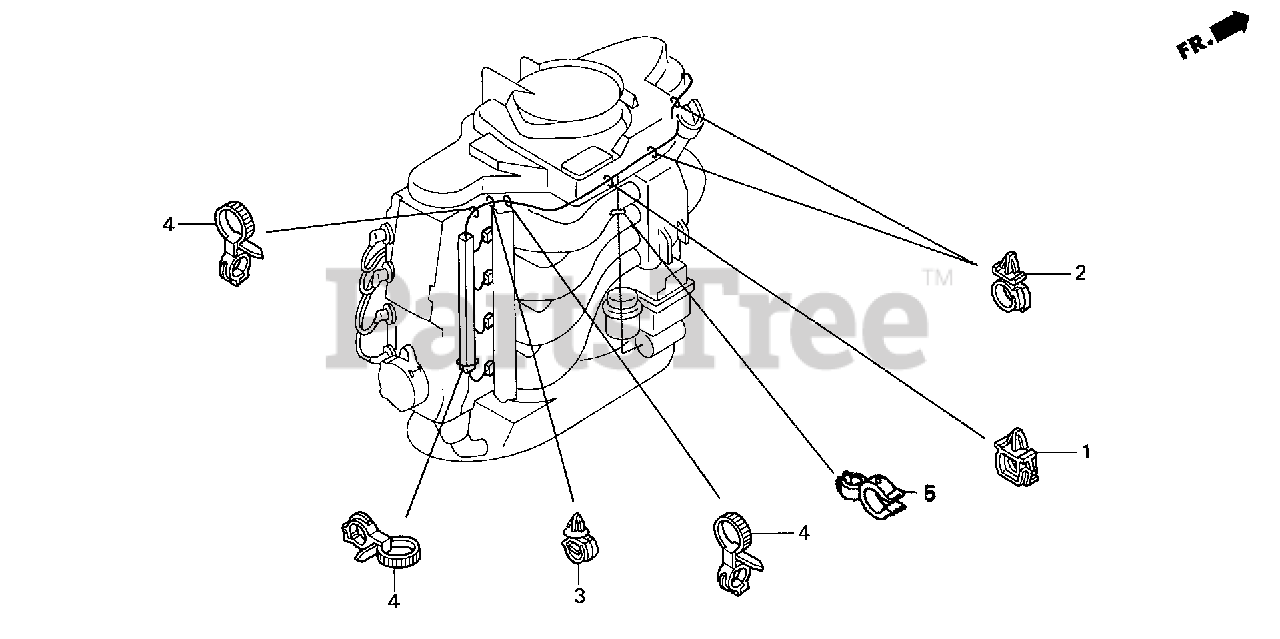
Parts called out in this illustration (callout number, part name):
1	CLIP, WIRE HARNESS (10MM)
2	CLIP, HARNESS
3	CLIP, HARNESS
4	CLIP, TUBE (135MM) (BLACK)
5	CLIP, SHIFT WIRE
